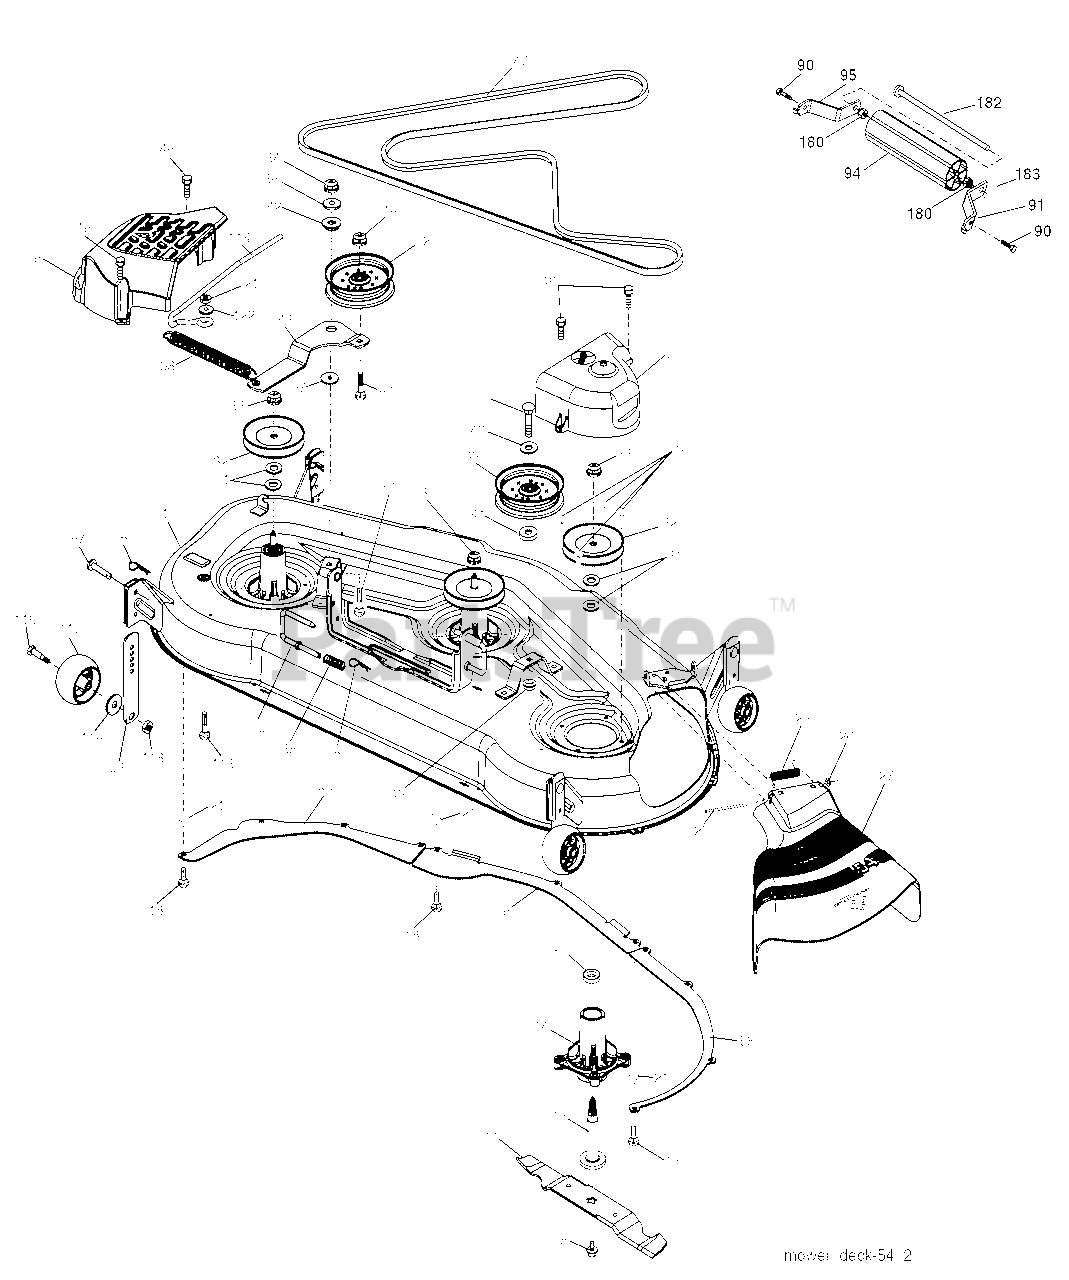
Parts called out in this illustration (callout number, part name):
1	Deck Weldment Mower
5	Retainer Spring
6	Cover Mandrel LH
7	Cover Mandrel RH
8	Bolt 7/16 Asm. Blade
11	Blade, Standard (For mulching mowers only)
13	Shaft Asm. w/Lower Bearing
14	Housing, Mandrel
15	Bearing, Ball, Mandrel
17	Bolt, Carriage 5/16-18 x 5/8
21	Nut, Crownlock 5/16-18 unc
25	Spring, Torsion
26	Nut, Push
27	Deflector Shield
29	Rod, Hinge
30	Screw, Thdroll Washer Head
31	Washer, Spacer Mower Vented
32	Pulley, Mandrel
33	Nut, Flg. Top Lock Cntr. 9/16
34	Nut
35	Pin Suspension Rear
38	Spring Compression
39	Pulley, Idler, Stationary
40	Washer 13/32 x 13/16 x 12 Ga.
41	Washer 13/32 x 1-3/8 x 3 Ga.
42	Spacer, Retainer
43	Arm, Idler
46	Screw, Thdroll. 1/4-20 x 5/8
47	V-Belt, Mower, Secondary
49	Nut, Lock Flg. 3/8-16 unc
50	Bolt, Carr. 3/8-16 x 2
51	Bolt
52	Pulley Idler Clutching
53	Bolt Fin Hex 3/8-16 unc x 2-1/4
56	Bar Pnt Adj.
57	Pin Head Rivet
58	Baffle Right
59	Baffle Left
60	Baffle Center
90	Bolt 5/16-18 x 1
91	Bracket Asm N Roller RH
94	Roller Nose 48"
95	Bracket Asm N Roller LH
97	Washer Hardened
98	Spring Clutch Drive
113	Bolt Rdhd Sqnk 5/16-18 x 3/4
114	Rod Tension Relief
116	Bolt, Shoulder
117	Gauge Wheel
118	Nut, Centerlock 3/8-16 unc
119	Washer 3/8 x 7/8 x 14 Ga.
122	Bushing Tension Relief
180	Nut 5/16-18
182	Rod Roller Nose Narrow
183	Retainer Spring
183	Mandrel Asm. Service
183	Replacement Mower, Complete
